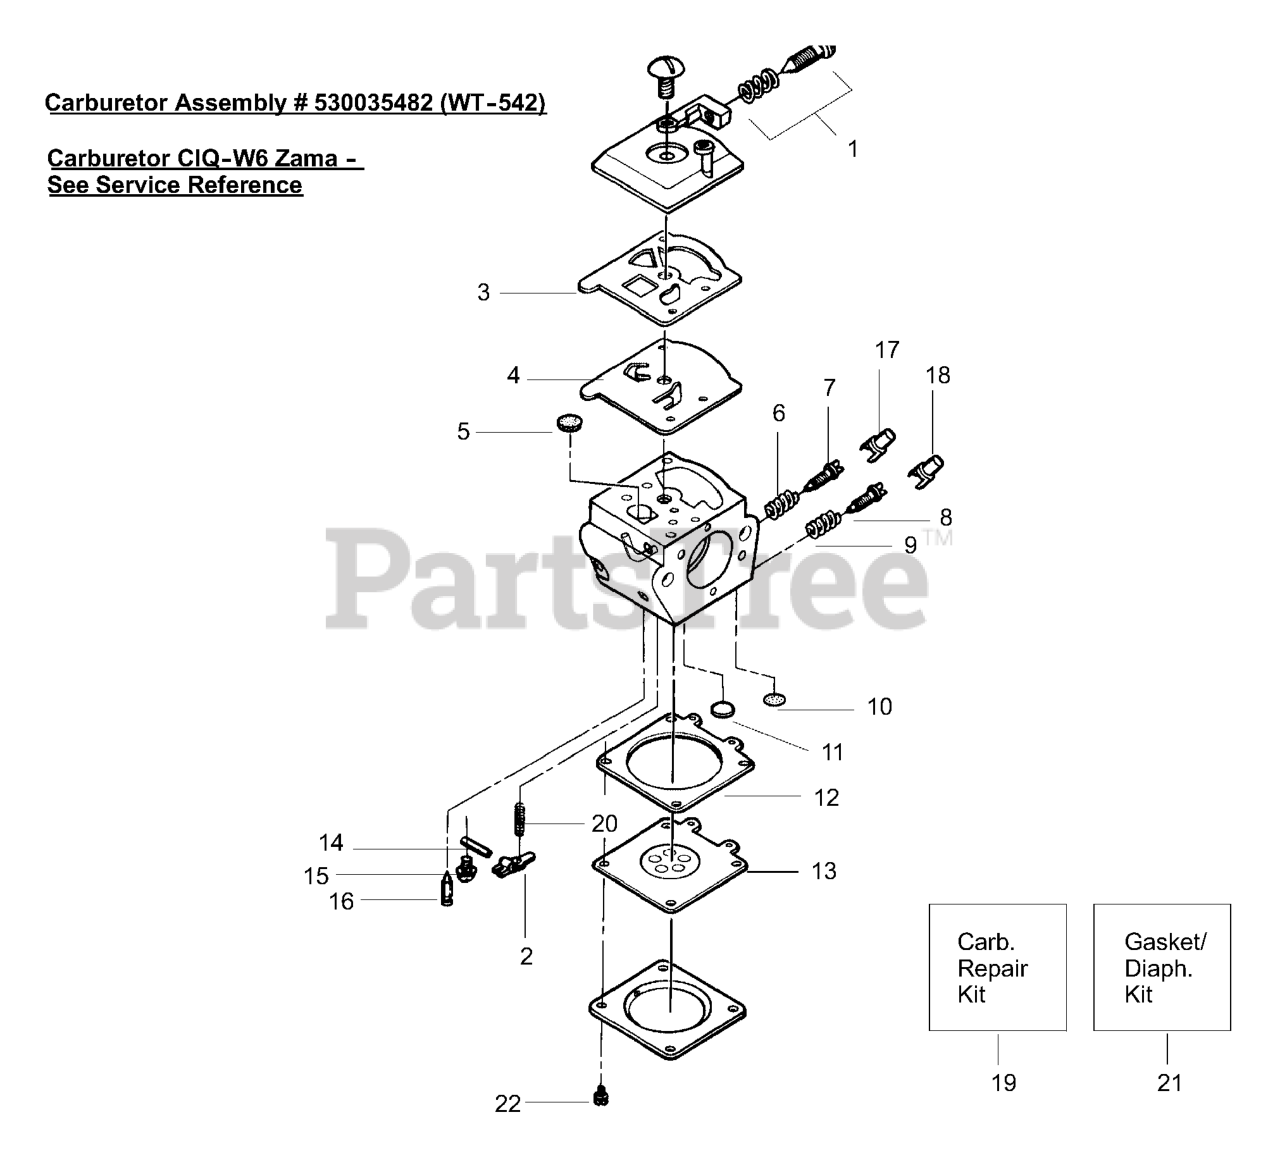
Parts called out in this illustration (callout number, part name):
1	IDLE ADV SCREW KIT
2	LEVER
3	GASKET-FUEL PUMP
4	DIAP FUEL PUMP
5	FILTER SCREEN
6	NEEDLE SPRING
7	LOW SPEED NEEDLE
8	High Speed Needle
9	NEEDLE SPRING
10	Welch Plug (5/16)
12	METERING DIA GASKET
13	DIAPHRAGM
14	PIN
16	INLET NEEDLEVALVE
17	LIMITER CAP (HIGH-RED)
18	LIMITER CAP (LOW-BLUE)
19	CARB REPAIR KIT
19	KIT, CARB REPAIR
20	SPRING-METERING LEVER
21	GASKET/DIAPHRAGM KIT
21	GASKET/DIAPHRAGM KIT ZAMA
22	SCREW, MOTOR COVER
530035482	CARBURETOR
